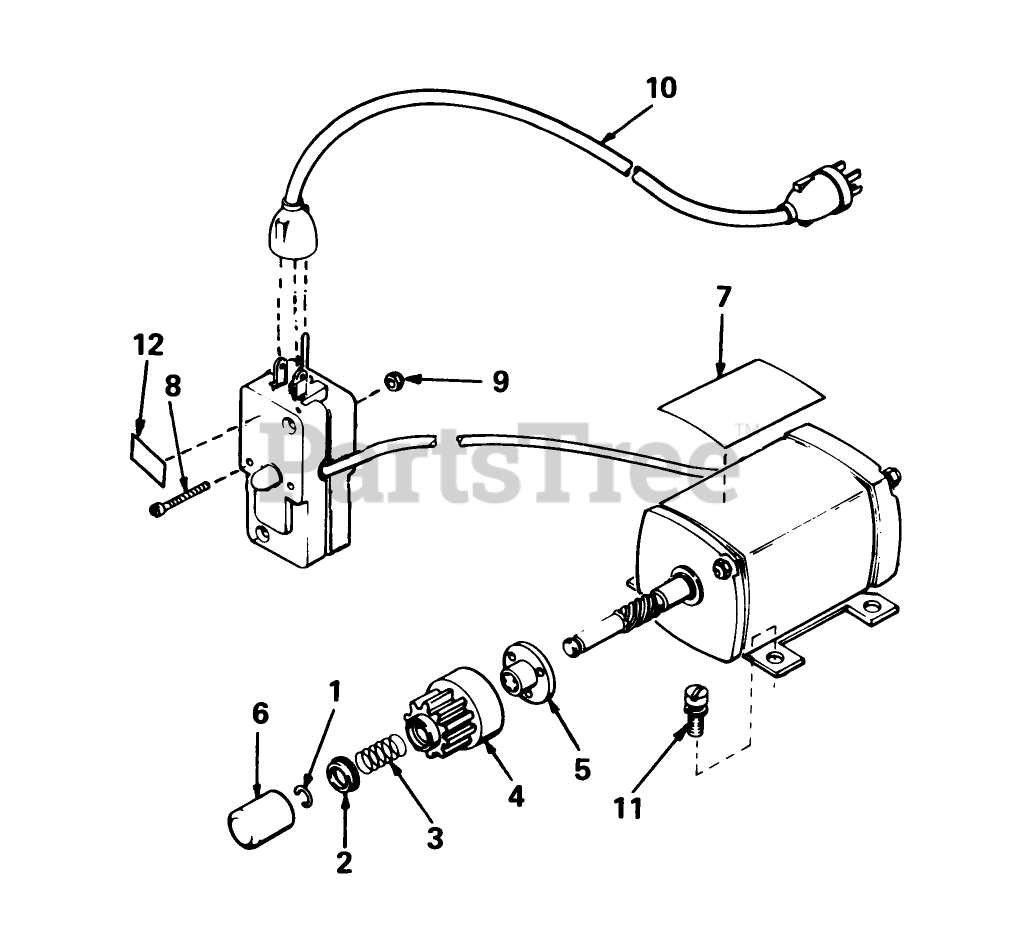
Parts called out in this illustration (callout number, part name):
1	Ring-Retainer
2	Retainer-Spring
3	Spring-Anti Drift
4	Gear
5	Nut-Engaging
6	Cover-Dust
7	39003A 5HP TILLER O
8	Screw, Pan Hd.
9	Nut Lockwasher
10	Cord-Extension
11	Screw
12	Decal
